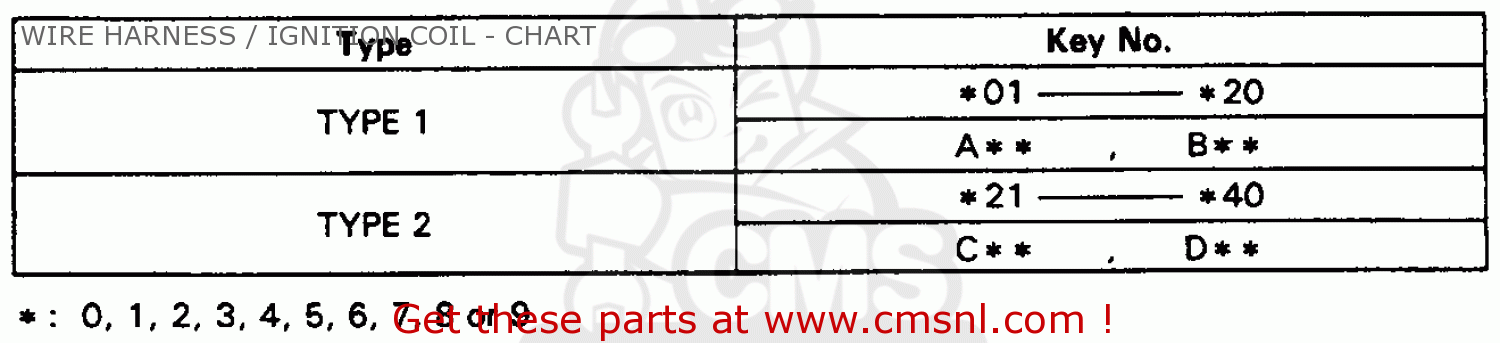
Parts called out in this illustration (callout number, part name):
1	COIL,IGNITION
3	CAP,SUPPRESSOR
6	RECTIFIER
7	STAY, RECTIFIER
9	HARNESS,WIRE
11	SUB-WIRE A
12	WIRE HARN.COVER
13	COVER, CONNECTOR
14	BAND,WIRE
15	GROMMET,M.SWITCH
16	KEY.SET
17	SW.ASSY.,COMB
18	KEY NO.1,BLANK
19	BOLT,HEX.,6X35
20	BOLT WASH 6X12
22	NUT-WASH.,6MM
23	SPG/WASHER,6MM
